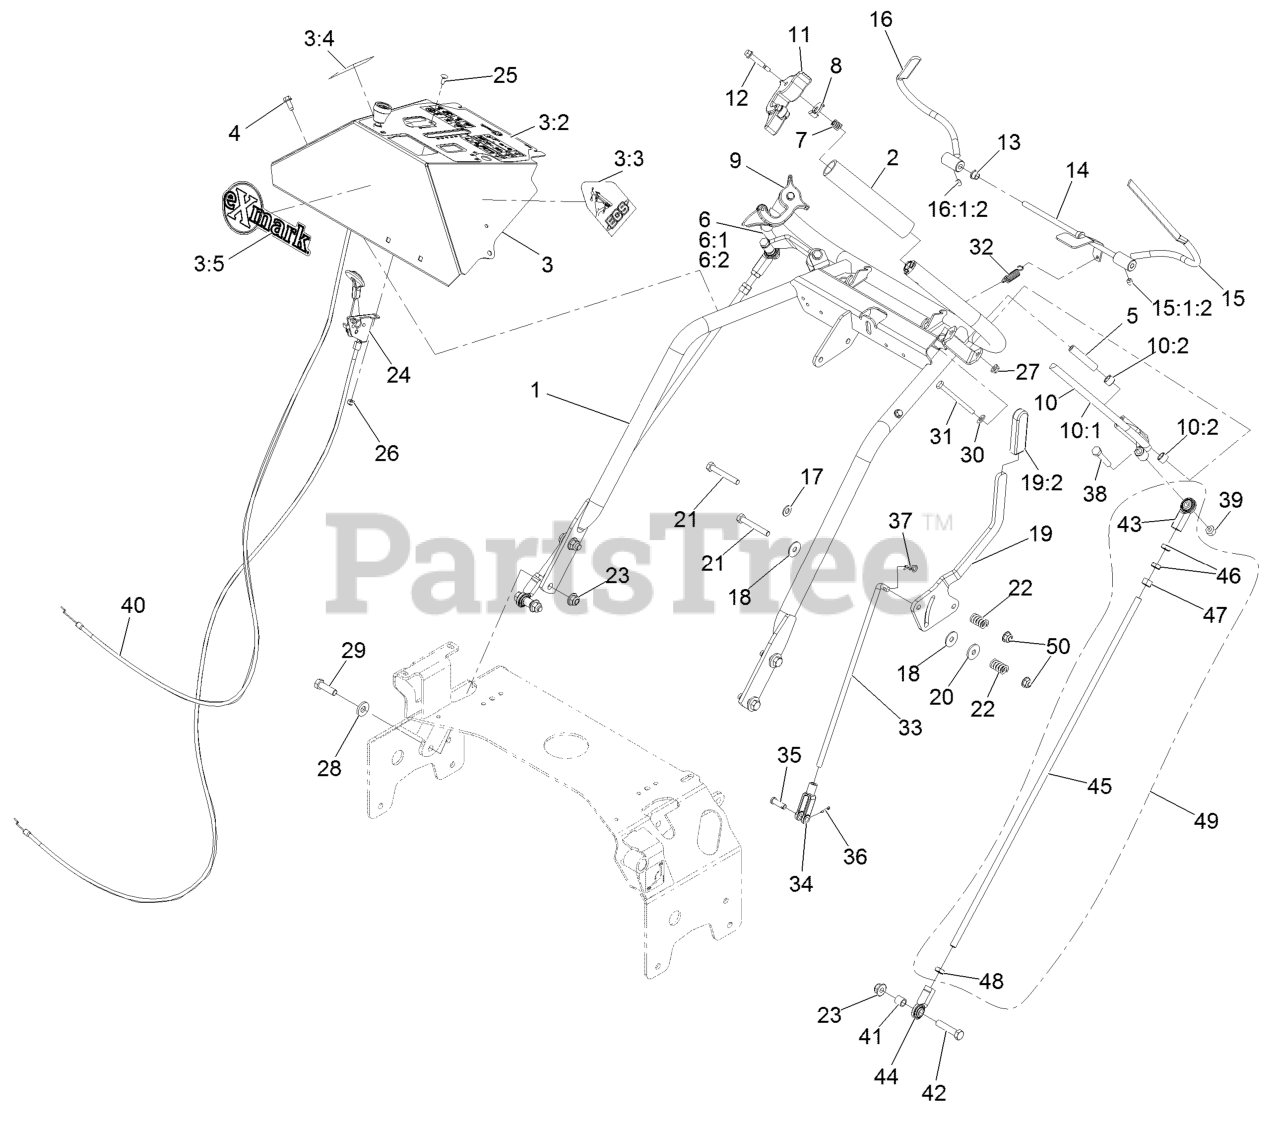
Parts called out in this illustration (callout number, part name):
1	WELD, HANDLE
2	GRIP-BAR, HANDLE
3	ASM, CONSOLE W/ DECALS
3:2	DECAL-CONSOLE TTX KAW
3:3	DECAL,LH ECS INSTRUCTION
3:4	DECAL,RH ECS INSTRUCTION
3:5	DECAL, EXMARK LOGO
4	SCREW-HWH
5	BUSHING-LEVER, DRIVE
6	DRIVE LEVER-ASM, RH
6:1	WLD,RH DRIVE LEVER
6:2	BUSHING-SLEEVE
7	SPRING-TANK, FUEL
8	LATCH, ECS
9	ASM,LATCH RH THUMB
10	DRIVE LEVER-ASM, LH
10:1	WLD,LH DRIVE LEVER
10:2	BUSHING-SLEEVE
11	ASM,LATCH LH THUMB
12	SCREW-SHOULDER
13	BUSHING-NYLON
14	WLD,OPC LEVER AXLE
15	WLD,LH OPC LEVER
15:1:2	SCREW-SET
16	WLD,RH OPC LEVER
16:1:2	SCREW-SET
17	WASHER-PLAIN
18	WASHER-FRICTION
19	LEVER, SHIFT W/GRIP
19:2	GRIP-HANDLE, STEERING
20	WASHER-FRICTION
21	SCREW-HH
22	SPRING-COMPRESSION
23	NUT-HF, NI
24	CONTROL-THROTTLE
25	BOLT-CARR
26	NUT-LOCK, NI
28	WASHER-BELLEVILLE
29	SCREW-HH
30	WASHER-FLAT
31	SCREW-HH
32	SPRING-EXTENSION
33	ROD,SPEED CONTROL
34	YOKE-ADJUSTABLE
35	PIN-CLEVIS
36	PIN-COTTER
37	PIN-COTTER
38	SCREW-HH
39	NUT-LOCK, NI
40	CABLE, CHOKE
41	SPACER-TUBE, PUMP LINK
42	SCREW-HH
43	JOINT-BALL, END
44	JOINT-BALL END, LH
45	LINK,DRIVE (PLTD)
46	NUT-HJ
47	NUT-HEX
48	NUT-HEX JAM, LH
49	DRIVE LINK ASM
50	NUT-HF, NI
